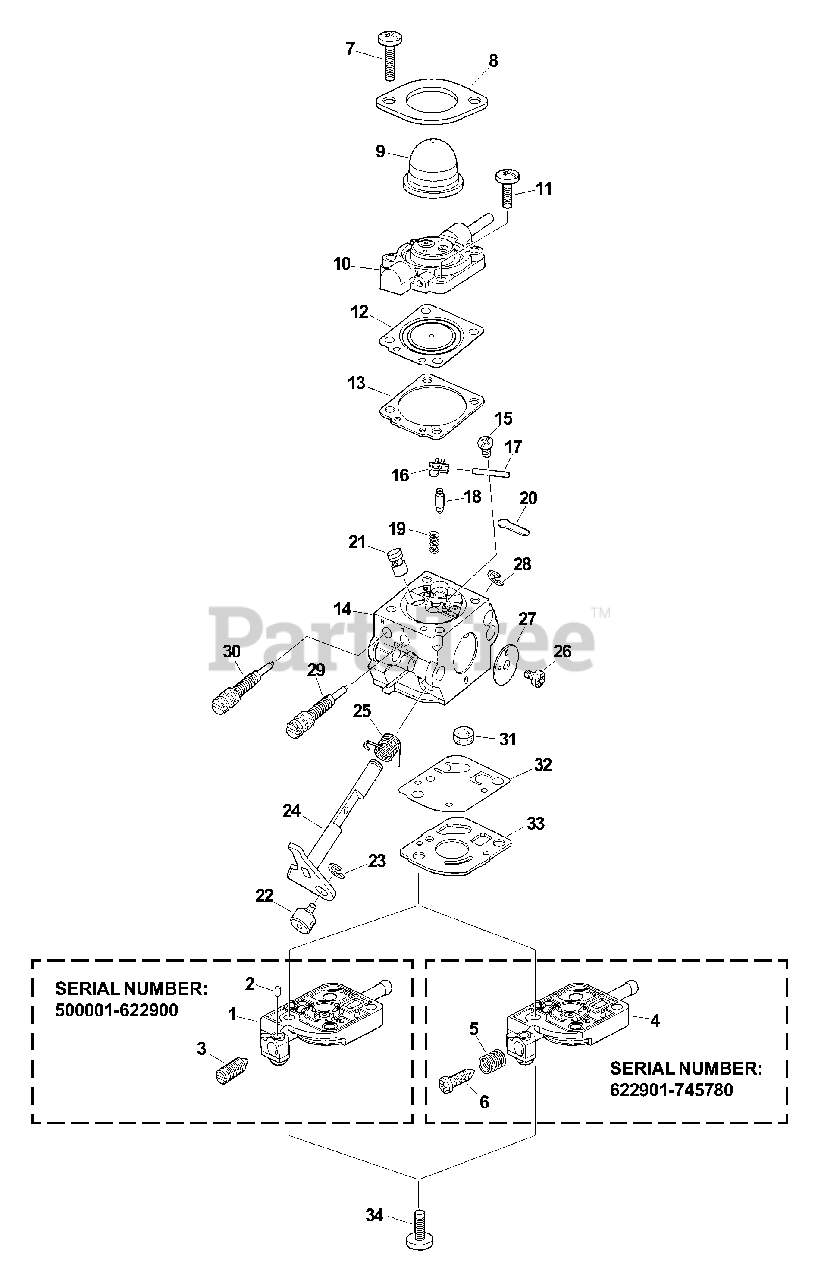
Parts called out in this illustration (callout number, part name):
1	COVER, PUMP
2	PIECE, FRICTION
3	SCREW, IDLE ADJUST
4	COVER, PUMP
5	SPRING, IDLE ADJUST
6	SCREW, IDLE ADJUST
7	SCREW, RETAINER
8	RETAINER, PURGE BULB
9	BULB, PURGE
10	BASE, PURGE
11	SCREW, PURGE BASE
12	DIAPHRAGM, METERING
13	GASKET, METERING
14	BODY, CARBURETOR
15	SCREW, METERING LEVER PIN
16	LEVER, METERING
17	PIN, METERING LEVER
18	VALVE, INLET NEEDLE
19	SPRING, METERING LEVER
20	PLUG, WELCH
21	NOZZLE, CHECK VALVE
23	RING, RETAINING
24	SHAFT, THROTTLE
25	SPRING, RETURN
27	VALVE, THROTTLE
28	RING, RETAINING
29	NEEDLE - LOW SPEED
30	NEEDLE - HIGH SPEED
31	STRAINER
32	DIAPHRAGM, PURGE
33	GASKET, PURGE
34	SCREW, PUMP COVER
